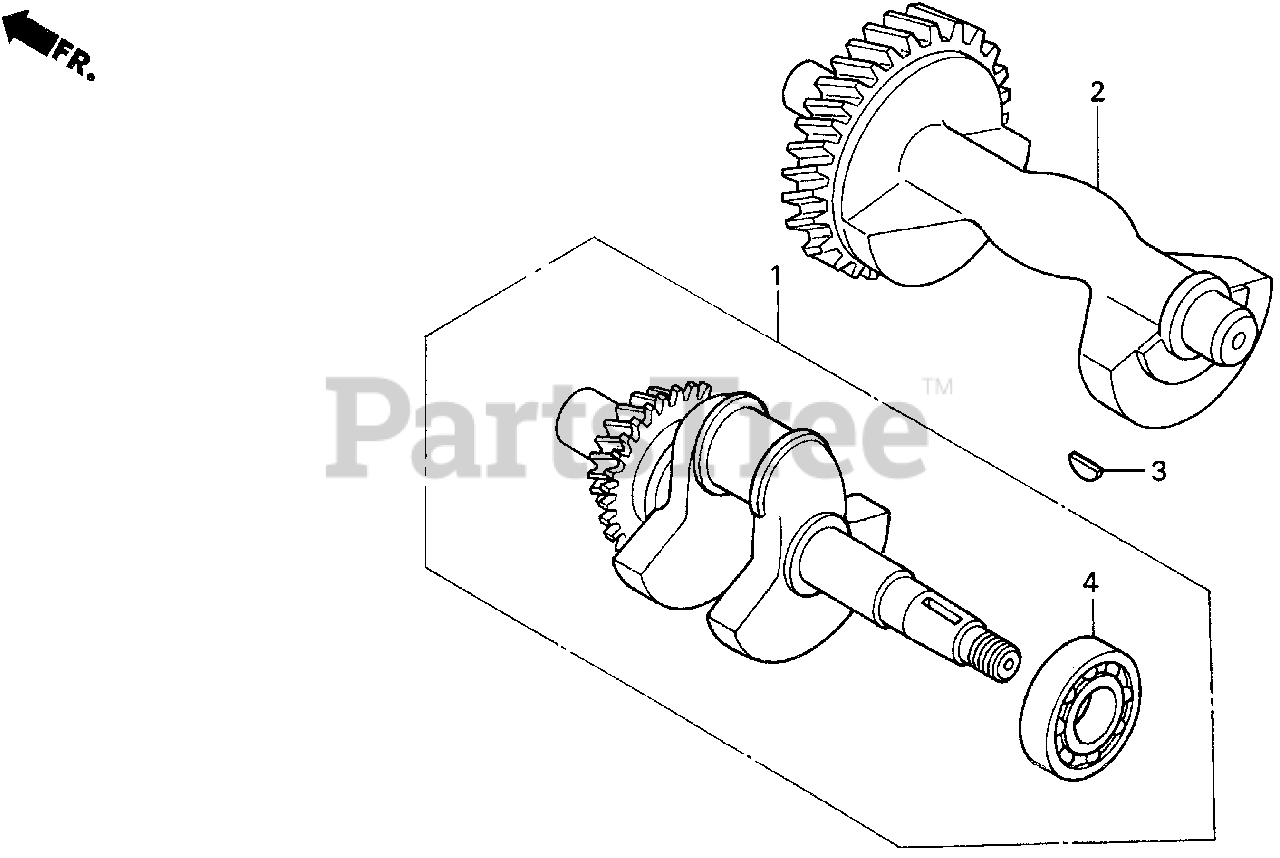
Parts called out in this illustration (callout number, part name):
1	CRANKSHAFT (EN-TYPE)
2	WEIGHT, BALANCER
3	KEY, SPECIAL WOODRUFF (25X18)
4	BEARING, RADIAL BALL (6207)
